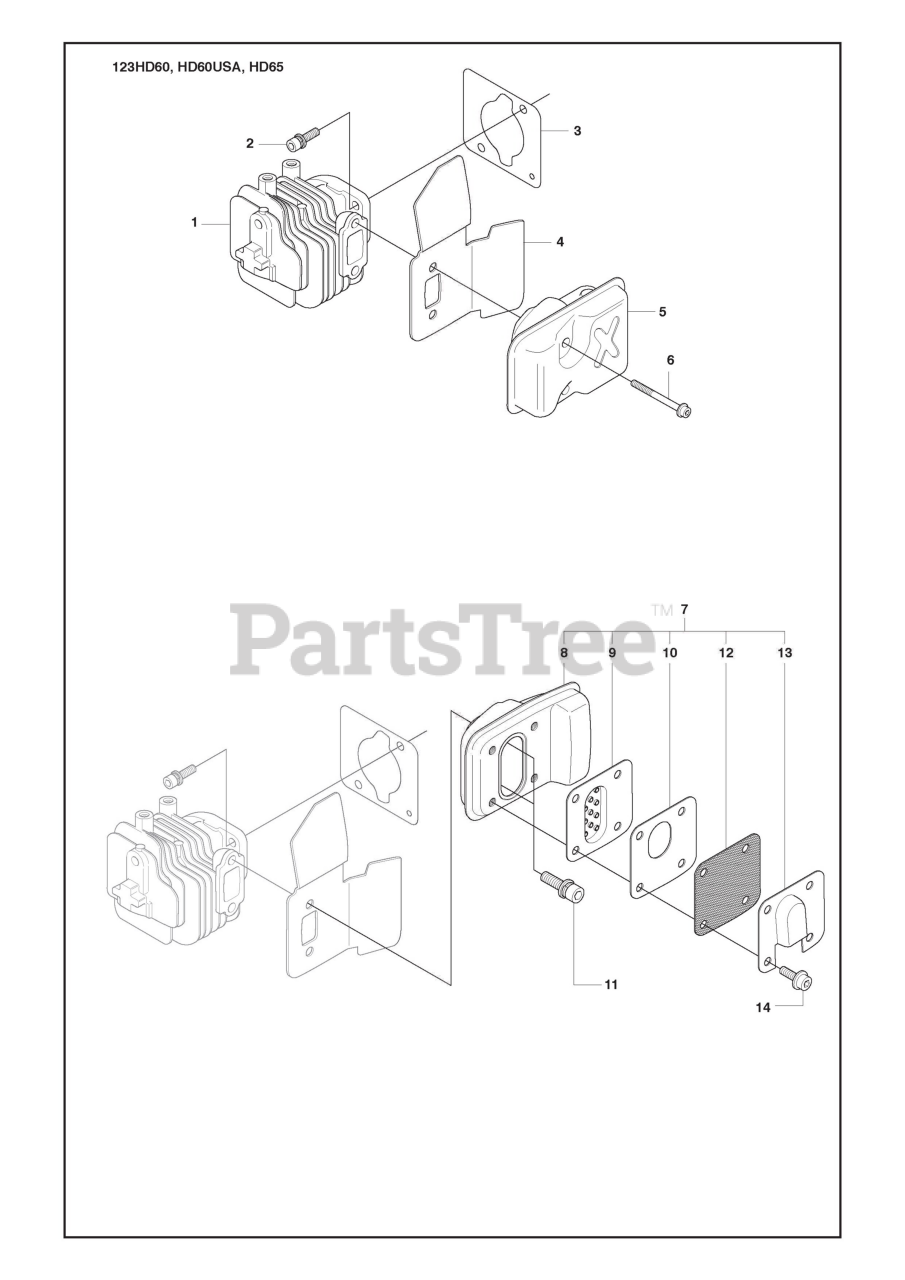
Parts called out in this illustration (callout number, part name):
1	CYLINDER/CARB
3	BASE GASKET
4	HEAT SHIELD/GASKET
7	MUFFLER ASSY
9	BAFFLE PLATE
10	BAFFLE PLATE
12	SPARK ARRESTER
13	EXHAUST DEFLECTOR
